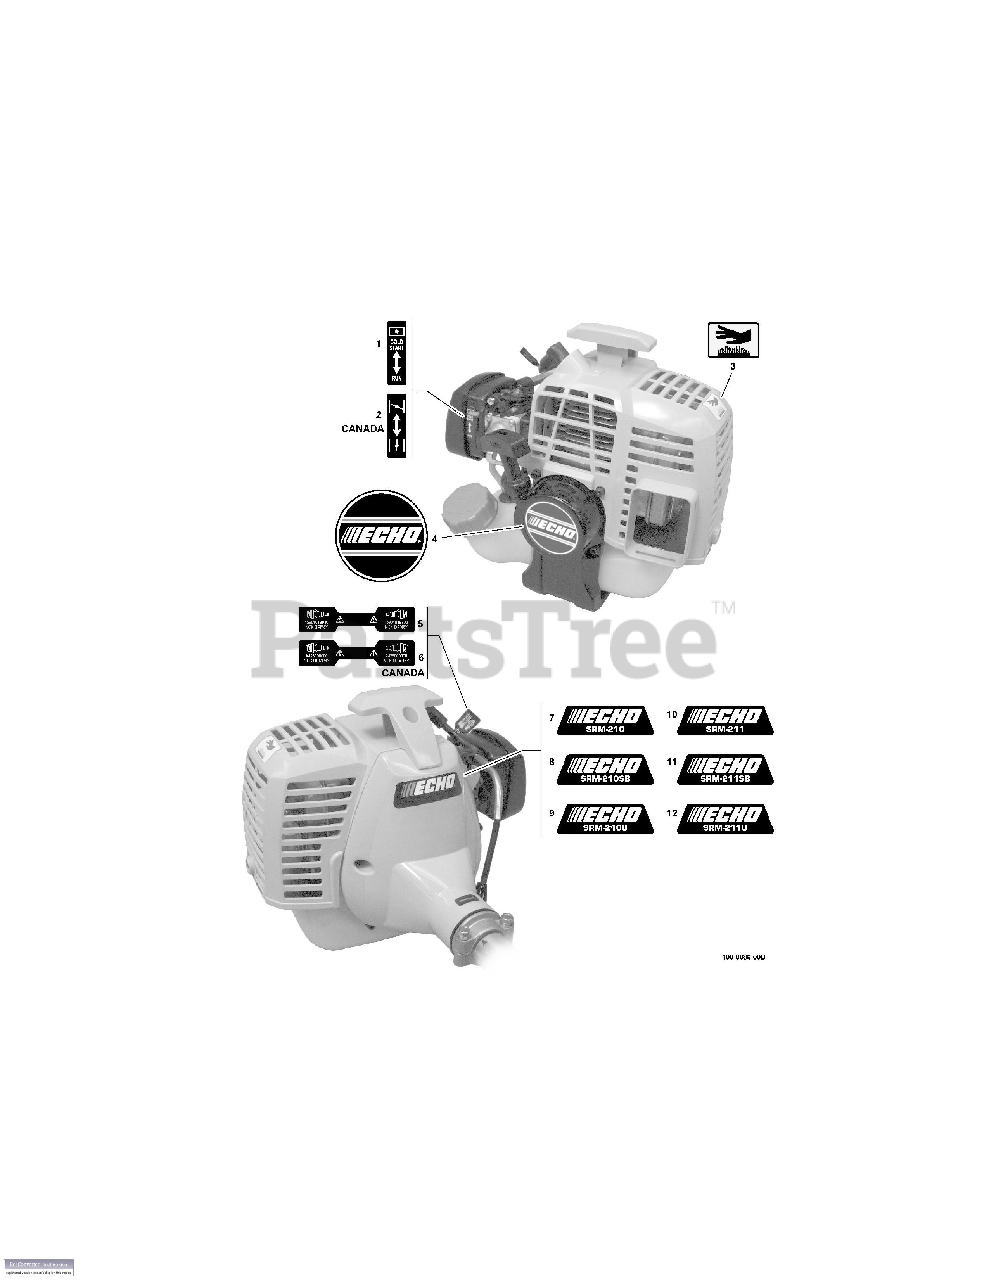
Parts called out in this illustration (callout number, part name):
1	LABEL - CHOKE
2	LABEL - CHOKE
3	LABEL - HOT SURFACE
4	LABEL - ECHO
5	LABEL - SPARK PLUG -- BPM-8Y
6	LABEL - SPARK PLUG -- BPMR-8Y
7	LABEL - MODEL SRM-210
8	LABEL - MODEL SRM-210SB
9	LABEL - MODEL SRM-210U
10	LABEL - MODEL SRM-211
11	LABEL - MODEL SRM-211SB
12	LABEL - MODEL SRM-211U
